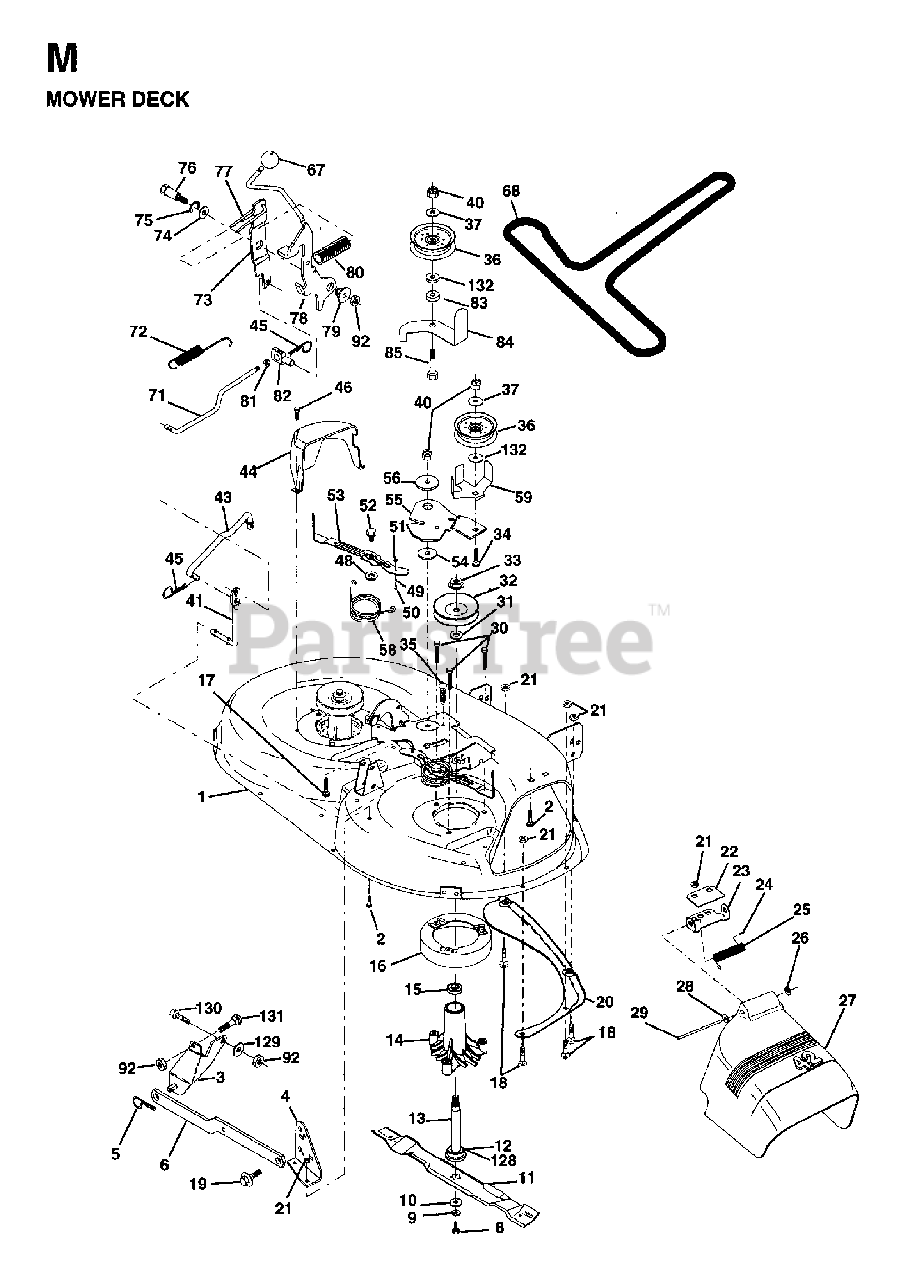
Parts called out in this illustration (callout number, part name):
1	DECK 42"
2	BOLT
3	BRKT ASM SWAY BAR
4	BRKT DECK SW BAR
5	RETAINER-SPRNG RB
6	REAR SUSP ARM
8	BLADE BOLT
9	LOCKWASHER
10	WASHER.BLADE
12	BEARING
13	SHAFT ASM VENT
14	HSG MANDREL
16	STRIPPER
17	BOLT
18	BOLT
19	BOLT SHD 5/16-18
20	BAFFLE
21	LOCKNUT
22	STIFFENER BRACKET
23	DEFLECTOR BRACKET
24	CAP-SLEEVE LT
25	SPRING TORSION
26	NUT PUSH M
27	SHIELD.DEFLECTOR.MOWER.42".BLK
28	WASHER
29	ROD.HINGE
30	SCREW
31	WASHER
32	PULLEY/MANDREL
33	NUT
34	BOLT
35	FASTENER.XMAS.TREE
36	FLAT IDLER PULLEY
40	LOCKNUT
41	PIVOT ROD
43	CLUTCH ROD
44	GUARD MANDREL LH BLACK
45	RETAINER M
46	SCREW.1/4-20X5/8
49	ROLLER ASSY
50	BOLT
53	ARM ASM PAD BRAD
54	HARDENED WASHER
55	ARM IDLER 42" MOWER LT/YT
56	SPACER RETAINER
59	GUARD, BELT
67	KNOB T (3/8 HOLE)
68	BELT
71	CLUTCH ROD
72	RETURN SPRING
73	ARM CLUTCH SECONDARY
75	RING CLIP
77	KEEPER SPRING
78	ARM ASM CLUTCH PRIMARY
79	BUSHING.FLANGE.E-RING.GROOVE
80	SPRING-CLUTCH
81	NUT
84	KEEPER.BELT.IDLER
85	BOLT
92	NUT
128	WASHER FELT
129	WASHER
131	BOLT D
132	WASHER GT
